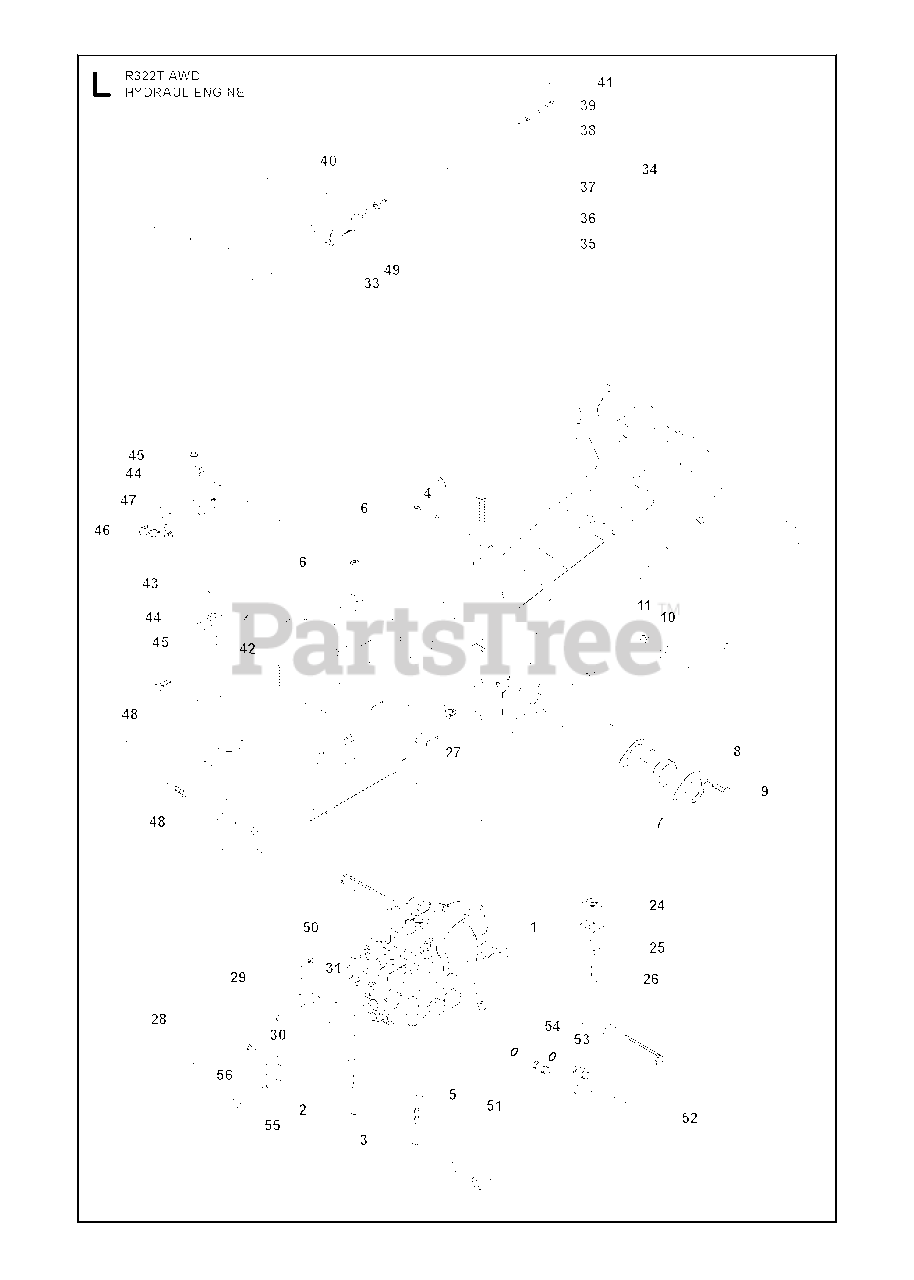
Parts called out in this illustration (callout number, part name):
1	TRANSMISSION SWE
5	WASHER BRB 8.4X17
6	LOCKNUT M8
8	BEARING HOUSING
9	BOLT
10	WASHER BRB 8.4X17
11	LOCKNUT M8
24	PIPE CLAMP
25	COVER PLATE
26	SCREW EHHFM
29	FUEL TANK BUSHING
34	ROD
42	LOCKNUT M6
45	SCREW EHHFM
46	ADJUSTING ROD
47	LOCKNUT M6
48	Screw, M10 X 25
50	LOCKNUT M6
51	HYDRAULIC PIPE
52	HYDRAULIC PIPE
53	PIPE FITTING
56	Screw
